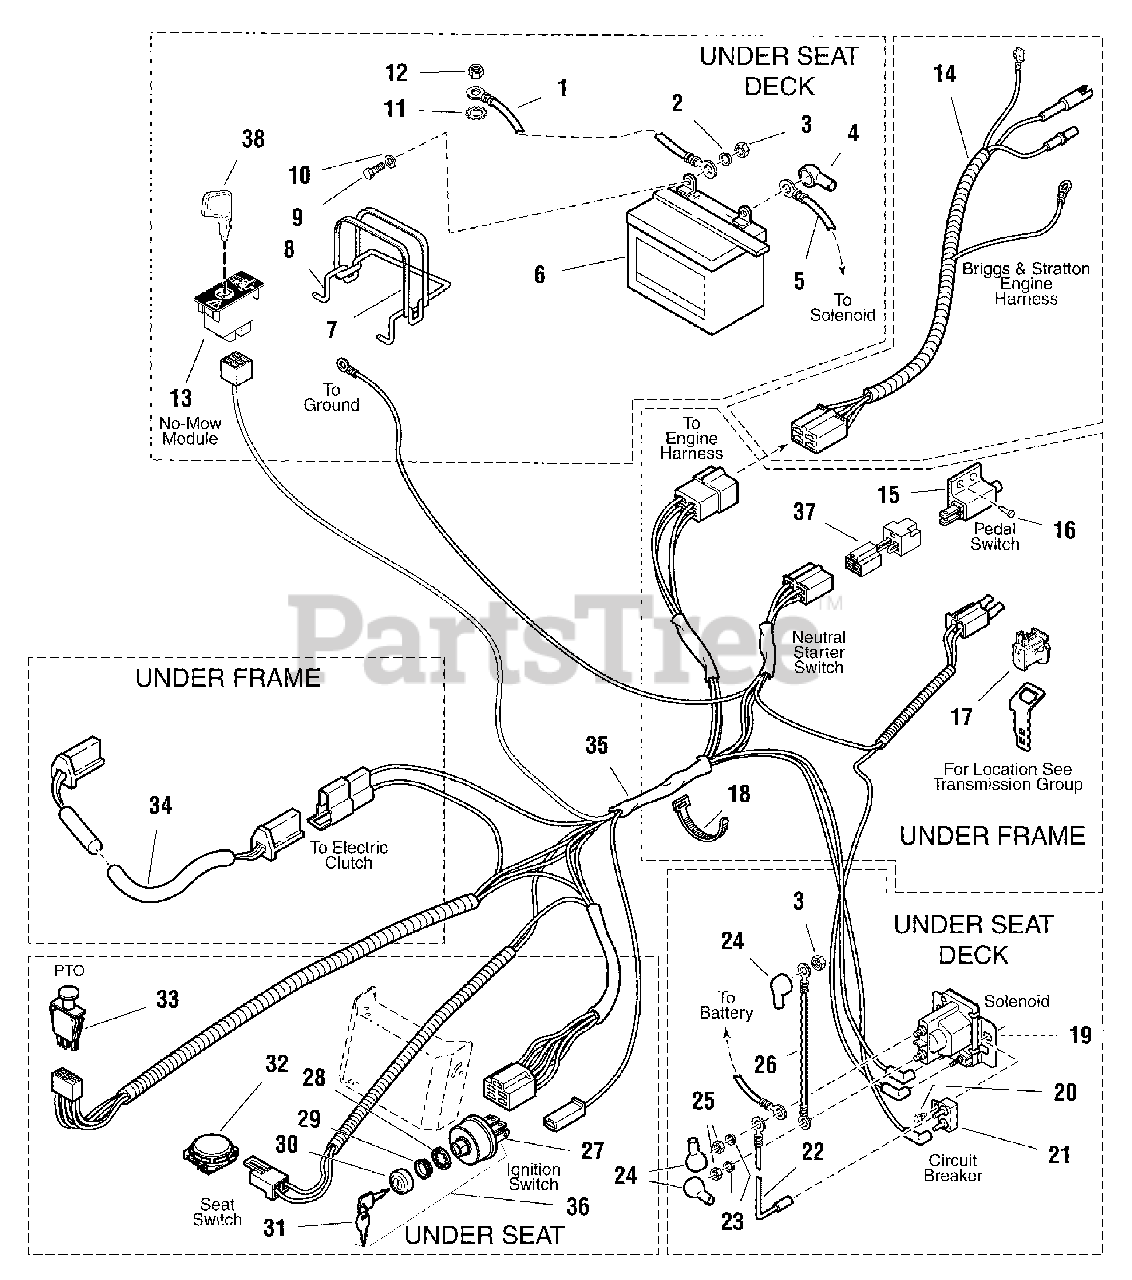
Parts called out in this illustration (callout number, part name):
1	CABLE, Battery to Ground
2	WASHER, Lock, 1/4
3	NUT, Hex 1/4-20
4	BOOT, Insulator
5	CABLE, Battery to Solenoid
7	STRAP, Battery
8	BRACE, Battery
9	CAPSCREW, Hex Head, 1/4-20 x 3/4
10	WASHER
11	WASHER, Lock, External Tooth, 3/8
12	NUT, Hex, 3/8-16
13	SWITCH, RMO Module Only
14	WIRE ASSEMBLY, Harness to Engine (Briggs & Stratton Only)
15	SWITCH, Neutral Start
17	SWITCH, Push Button (N.O.)
18	TIE, Self-Locking
19	SOLENOID
20	CAPSCREW, Hex Head, Taptite, 1/4-20 x 1/2
21	CIRCUIT BREAKER
22	WIRE ASSEMBLY
23	LOCKWASHER, 5/16
24	COVER, Terminal
25	NUT, Hex, 5/16-24
26	CABLE, Solenoid to Starter
27	SWITCH, Ignition (6 pole)
28	WASHER, Internal Tooth, 5/8
29	NUT
30	COVER, Keyswitch
31	KEYS (Set of 2 Keys)
32	SWITCH, Seat
33	* SWITCH, PTO, Electric Clutch
34	WIRE HARNESS, Clutch
35	HARNESS, Wiring
36	IGNITION KEY SWITCH ASSEMBLY
37	WIRING ASSEMBLY, All Conditions Shutdown
38	KEY, RMO Module, Plastic
